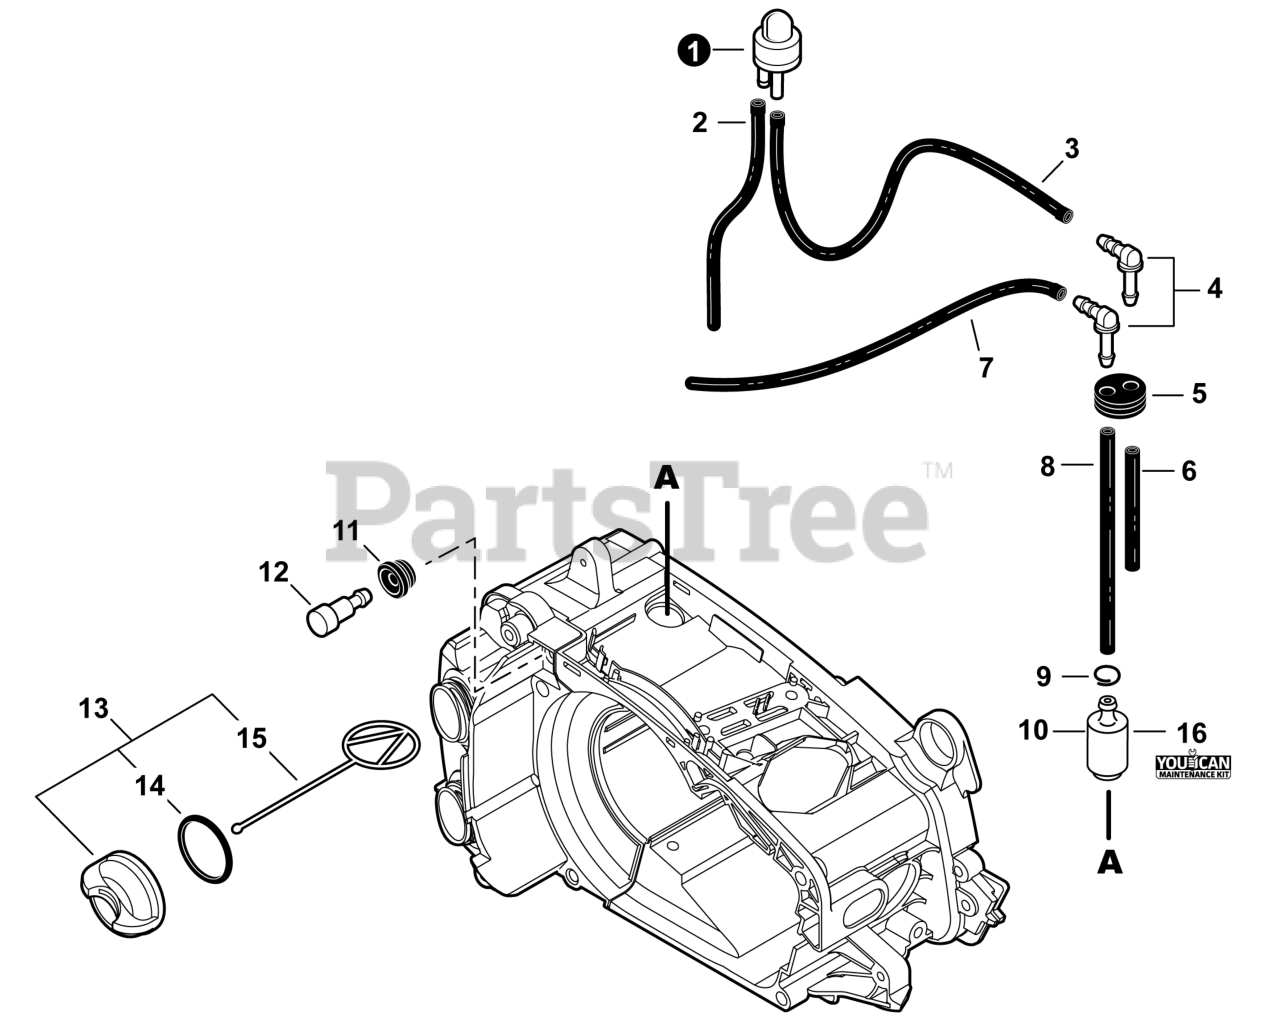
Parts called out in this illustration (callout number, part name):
1	BULB, PURGE
2	PIPE 2.4×5×180 - BLACK
3	PIPE 2.4×5×400 - BLACK
4	CONNECTOR, PIPE
5	GROMMET, FUEL
6	PIPE 2.4×5×15 - BLACK
7	PIPE, FUEL - 3*5*265 2020
8	PIPE 3×5×140 - BLACK
9	CLIP Ø6
10	FILTER, FUEL
11	GROMMET, FUEL
12	VENT ASSY
13	CAP ASSY, FUEL - ORANGE
15	FUEL CAP CONNECTOR (L=60MM)
16	TUNE-UP KIT - YOUCANT
